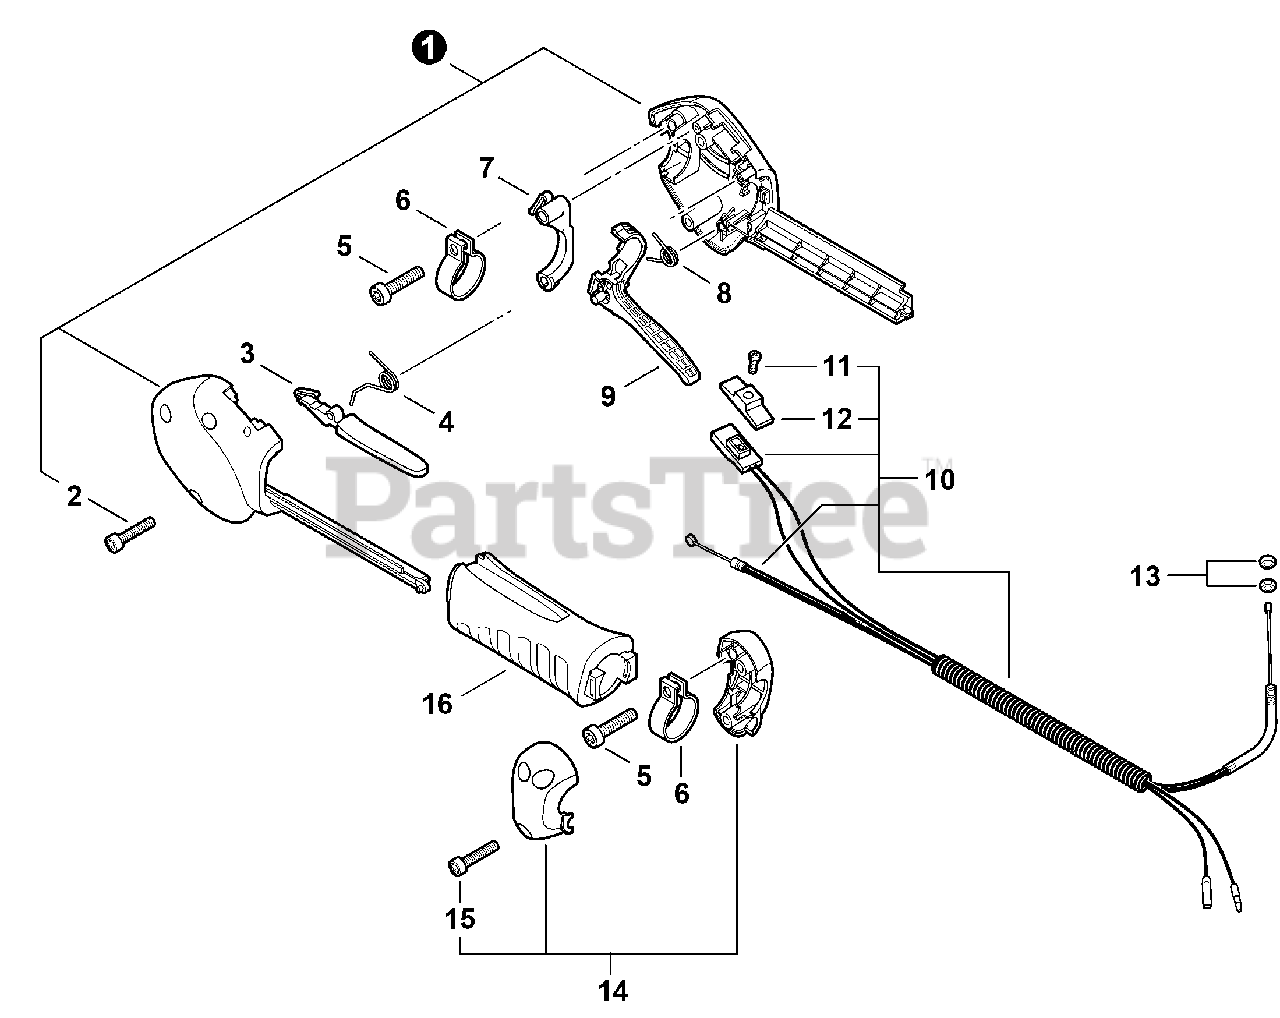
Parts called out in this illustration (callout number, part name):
1	HANDLE KIT, CONTROL
3	LEVER, THROTTLE LOCKOUT
4	SPRING, TORSION
5	BOLT 5×20
7	LOCKOUT, THROTTLE
8	SPRING, TORSION
9	TRIGGER, THROTTLE
10	CABLE ASSY, CONTROL
11	SCREW 3×10
12	KNOB, SWITCH - ORANGE
14	FIXTURE SET, HANDLE
16	GRIP, HANDLE
